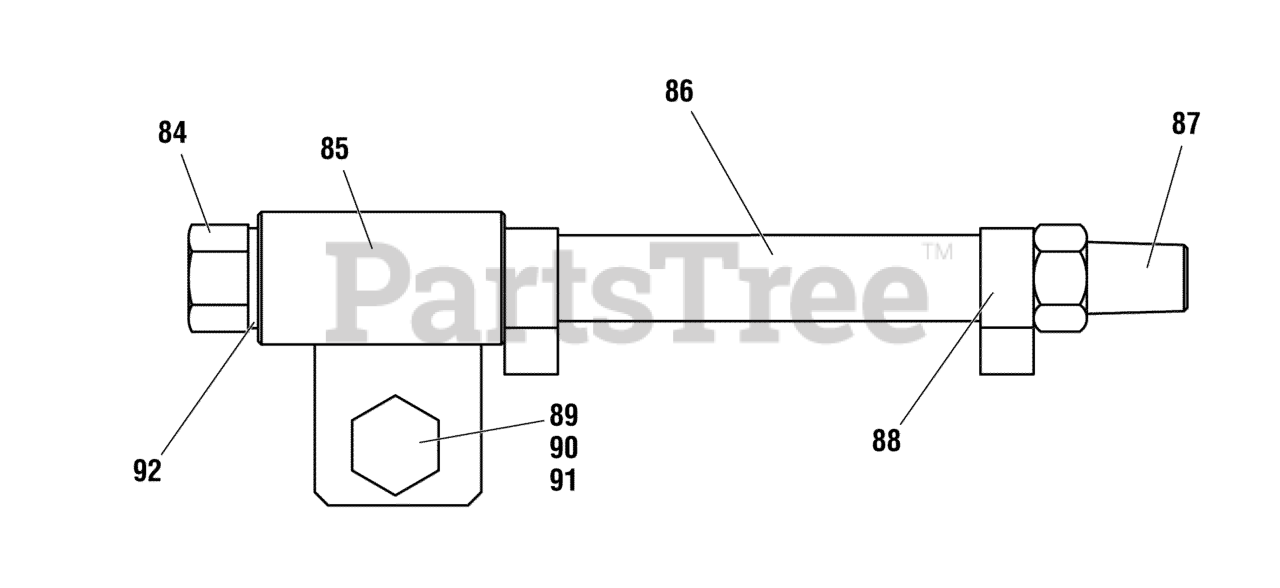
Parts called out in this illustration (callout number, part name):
84	PLUG, Hex Head
85	NOZZLE
87	TAPER JOINT
88	SPRING CLAMP
89	BOLT, M8 x 20, GB5783
90	WASHER, Spring, 8, GB93
91	NUT, M8
92	GASKET, Sealing, 14
